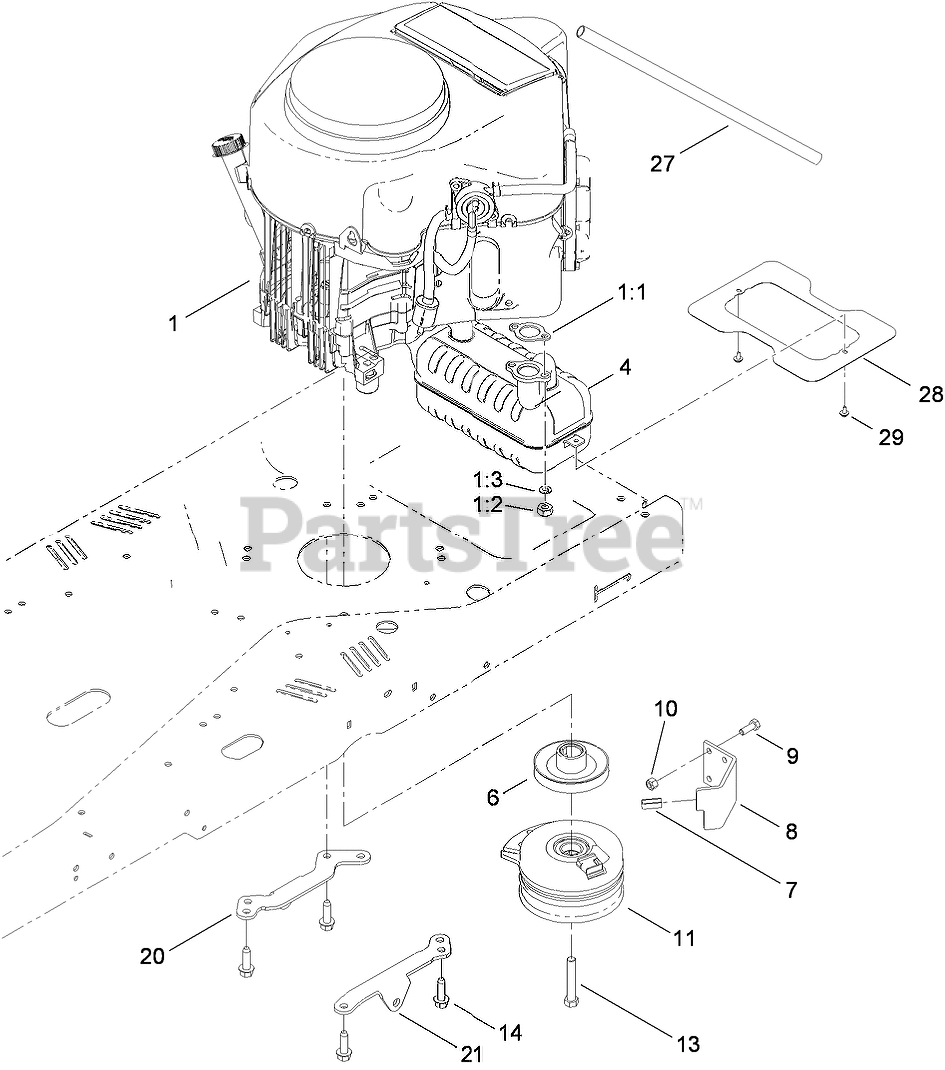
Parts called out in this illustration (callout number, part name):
1:1	GASKET-EXHAUST
1:3	WASHER-LOCK
4	MUFFLER-KAWASAKI
6	PULLEY-ENGINE
7	BUMPER-PAD
8	STOP-CLUTCH
9	SCREW-HH
10	NUT-LOCK, NI
11	CLUTCH-ELECTRIC, PTO
13	SCREW-HH
14	BOLT-HH
20	SUPPORT-HYDRO, RH
21	SUPPORT-HYDRO, LH
27	TUBE-DRAIN, OIL
28	SHIELD-HEAT
29	SCREW-HHFTF
